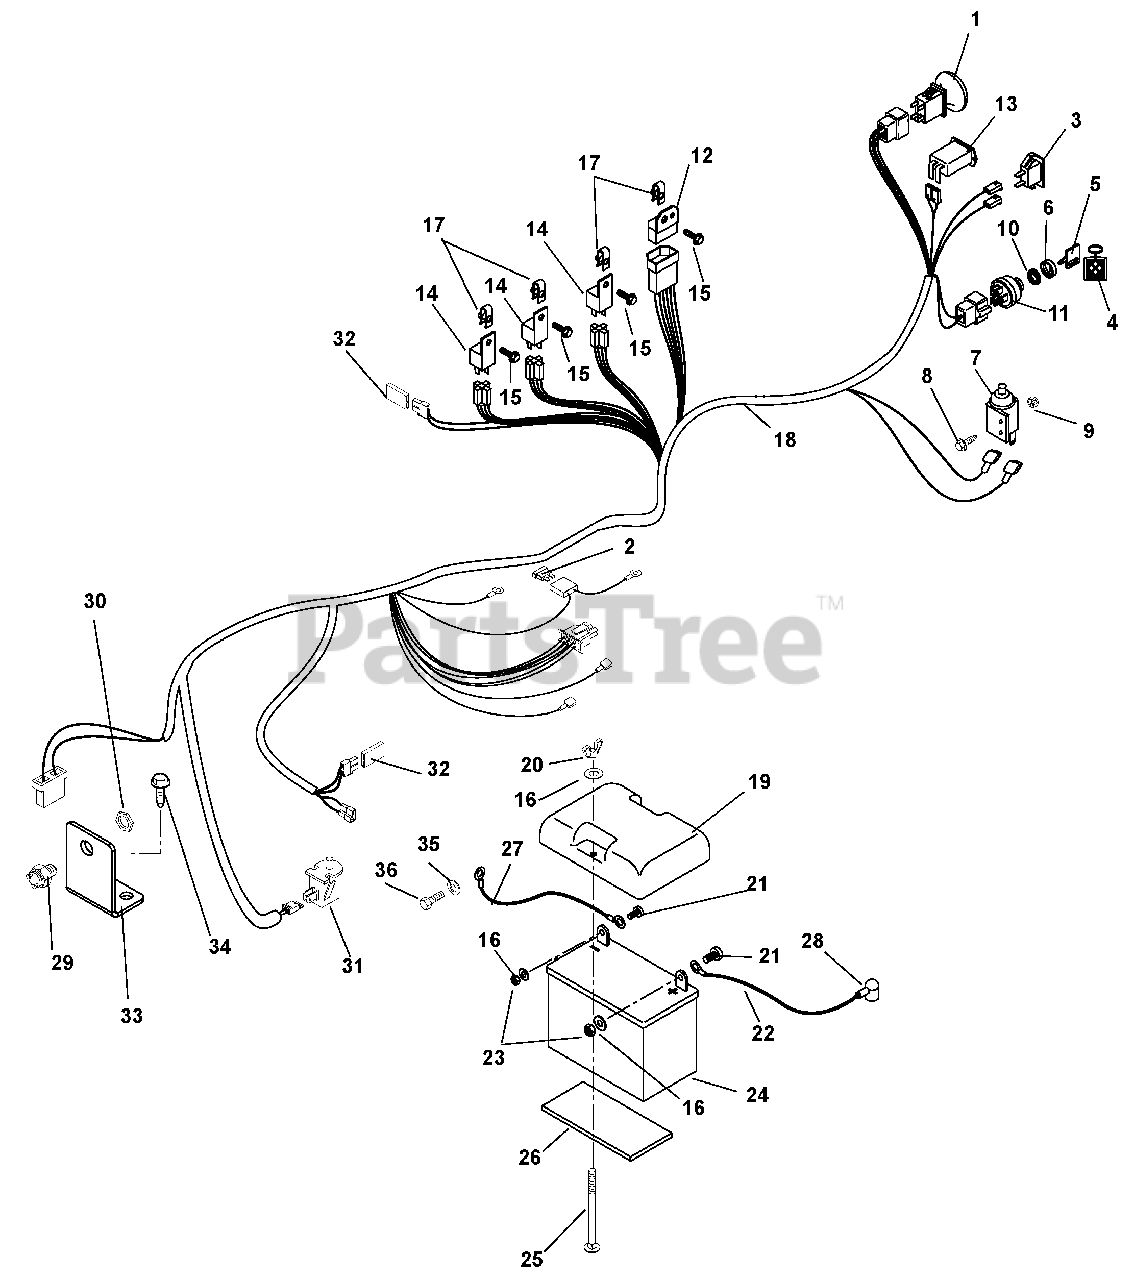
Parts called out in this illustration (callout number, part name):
1	Switch-Clutch with Retainer Ring
2	Fuse, 30 Amp (Included with Harness)
3	Light-Indicator
4	Key Chain
5	Key with Cap
6	Cap-Ignition Switch
7	Switch-Single Pole (N.O.) with Cover
8	Screw-Machine 10-24 x .50 Hex Washer Head
9	Nut-Locking-Nylon 10-24 with Insert
10	Nut-Panel .562-24
11	Key Switch
12	Module, Time Delay
13	Hour Meter
14	Relay (Included with Harness)
15	Screw-Machine 10-24 x .75 Hex Washer Head
16	Washer-Flat-Steel .281 x .620 x .065
17	Retainer Nut 10-24
18	Harness-Wiring
19	Cover-Battery
20	Nut-Locking-Wing .250-20
21	Bolt-Hex .25-20 x .75 Grade 5
22	Start Cable 22"
23	Nut-Locking-Center .25-20
25	Bolt-Round Head Square Neck .25-20 x 7.00 Grade 2
26	Pad, Battery
27	Cable, Negative Battery 35" Long
28	Battery Terminal Boot, Red
29	Switch, Neutral Start (N.C.)
30	Nut-Stamped .56-18
31	Switch, Seat (Included with Seat)
32	Diode, Connector Shell (Included with Harness)
33	Bracket, Neutral Switch
34	Screw, Tapping .25-20 x .50
35	Washer, Locking .31 x .078 Regular (023)
36	Bolt, Hex M8-1.25 x 20 (023)
